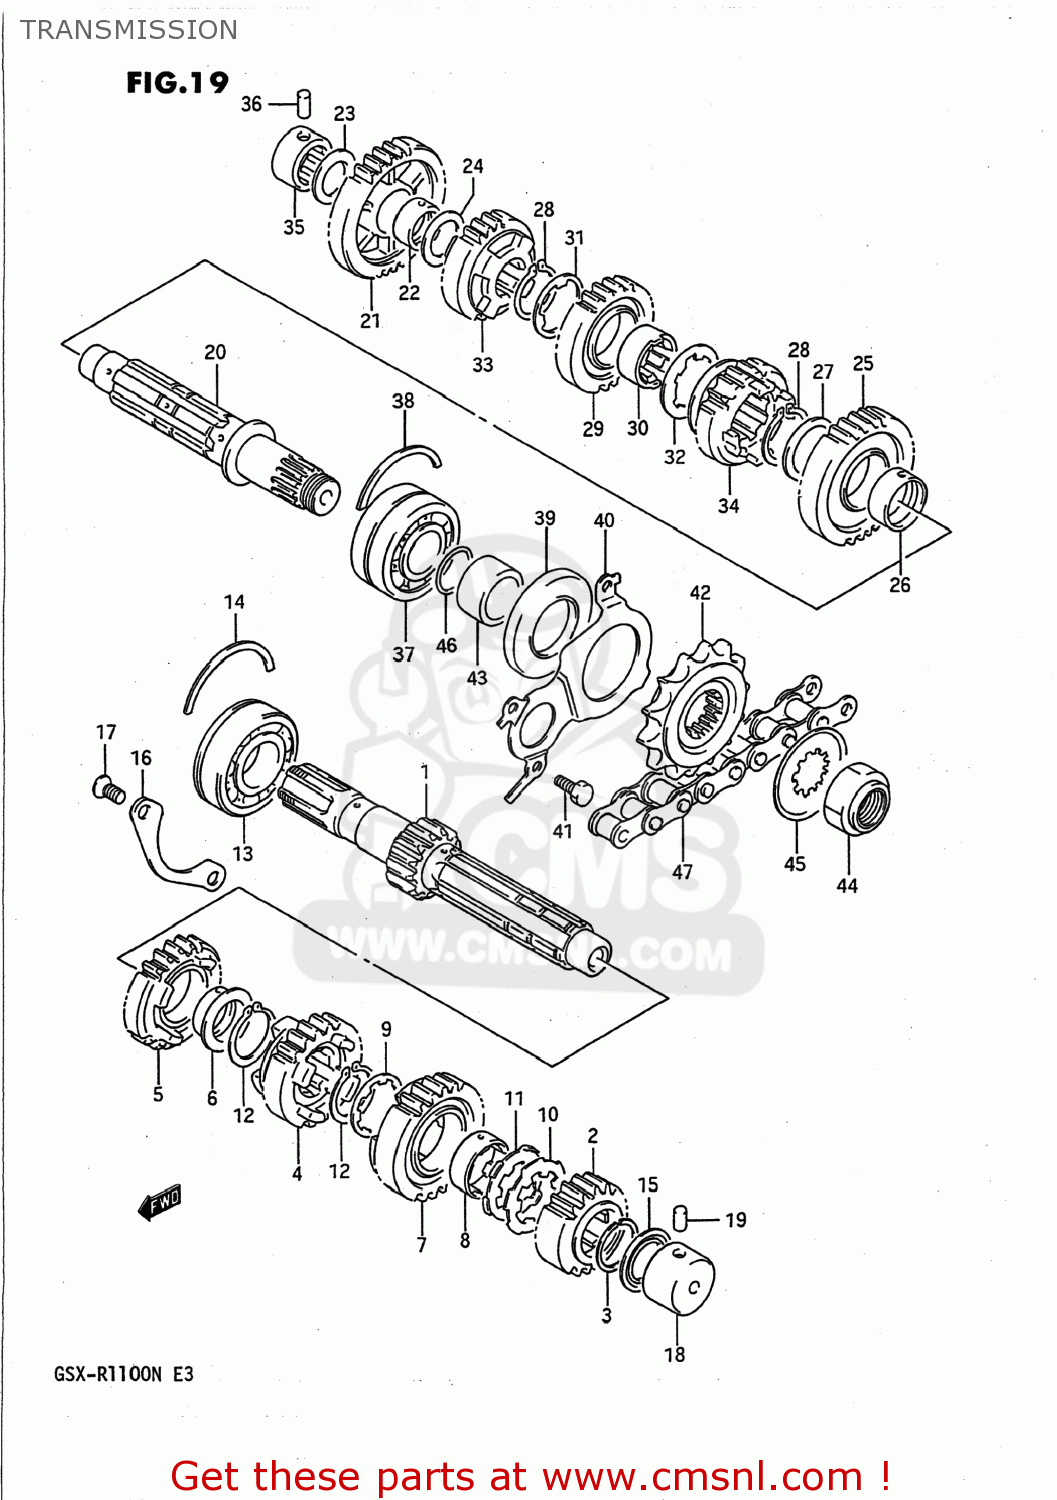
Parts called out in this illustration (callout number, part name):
1	SHAFT,COUNTER
2	GEAR,2ND DRIVE(NT:19)
3	CIRCLIP
4	GEAR,THIRD DRIVE (NT:20)
5	GEAR,FOURTH DRIVE (NT:22)
6	BUSHING
7	GEAR,FIFTH DRIVE (NT:23)
8	BUSH,5TH DRIVE GEAR
9	WASHER,LOCK
10	WASHER,LOCK
11	WASHER
12	RING,SNAP
13	BEARING(25X62X17)
14	C RING
15	SEAL,OIL(20X31.2X2.7)
16	RETAINER,CNTR SHAFT BEARING
17	SCREW
18	BEARING(20X34X17.5)
19	PIN
20	SHAFT,DRIVE
21	GEAR,FIRST DRIVEN
22	BUSHING
23	WASHER
24	WASHER
25	GEAR,SECOND DRIVEN
26	BUSH(28X32X11)
27	WASHER
28	CIRCLIP
29	GEAR,THIRD DRIVEN (NT:25)
30	BUSHING,THIRD DRIVEN GEAR
31	WASHER,LOCK
32	WASHER,LOCK
33	GEAR,FOURTH DRIVEN (NT:23)
34	GEAR,FIFTH DRIVEN
35	BEARING(20X34X20)
36	PIN
37	BEARING(25X62X21.6)
38	C RING
39	SEAL,OIL(34X62X6)
40	RETAINER,DRIVE SHAFT OIL SEAL
41	BOLT
42	SPROCKET,ENGINE(15T)
43	SPACER (25X34X18.1)
44	NUT
45	WASHER,LOCK
46	O RING(D:1,ID:24.5)
47	CHAIN,DRIVE(118LE)
